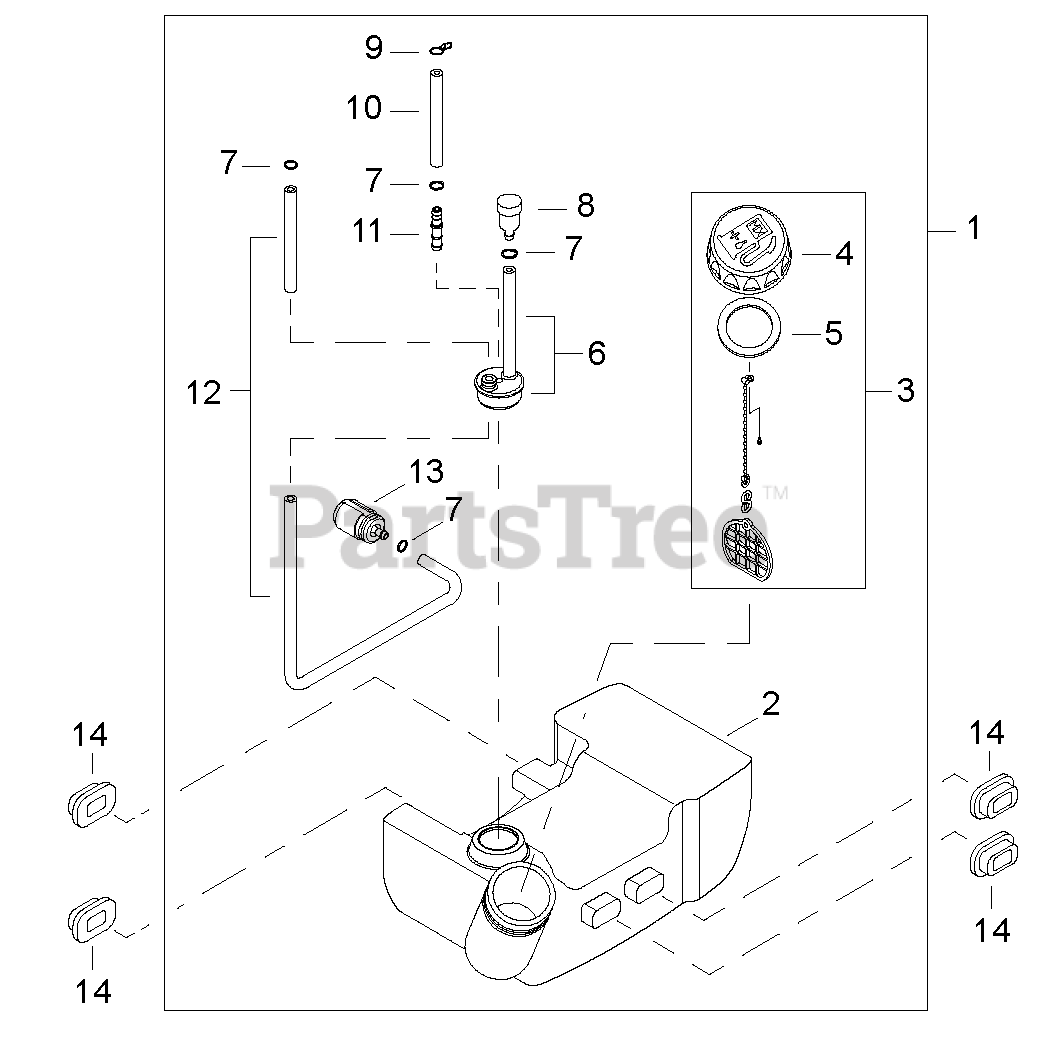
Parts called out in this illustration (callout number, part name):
1	FUEL TANK ASSY
2	TANK, FUEL
3	CAP ASSY
4	CAP, FUEL
5	GASKET, CAP
6	GROMMET
7	RING, RETAINING - 6
8	ELEMENT, BREATHER
9	CLIP - SPRING
10	PIPE - 50 -- BLACK
11	CONNECTOR, PIPE
12	PIPE - FUEL
13	FILTER, FUEL
14	CUSHION, FUEL TANK
